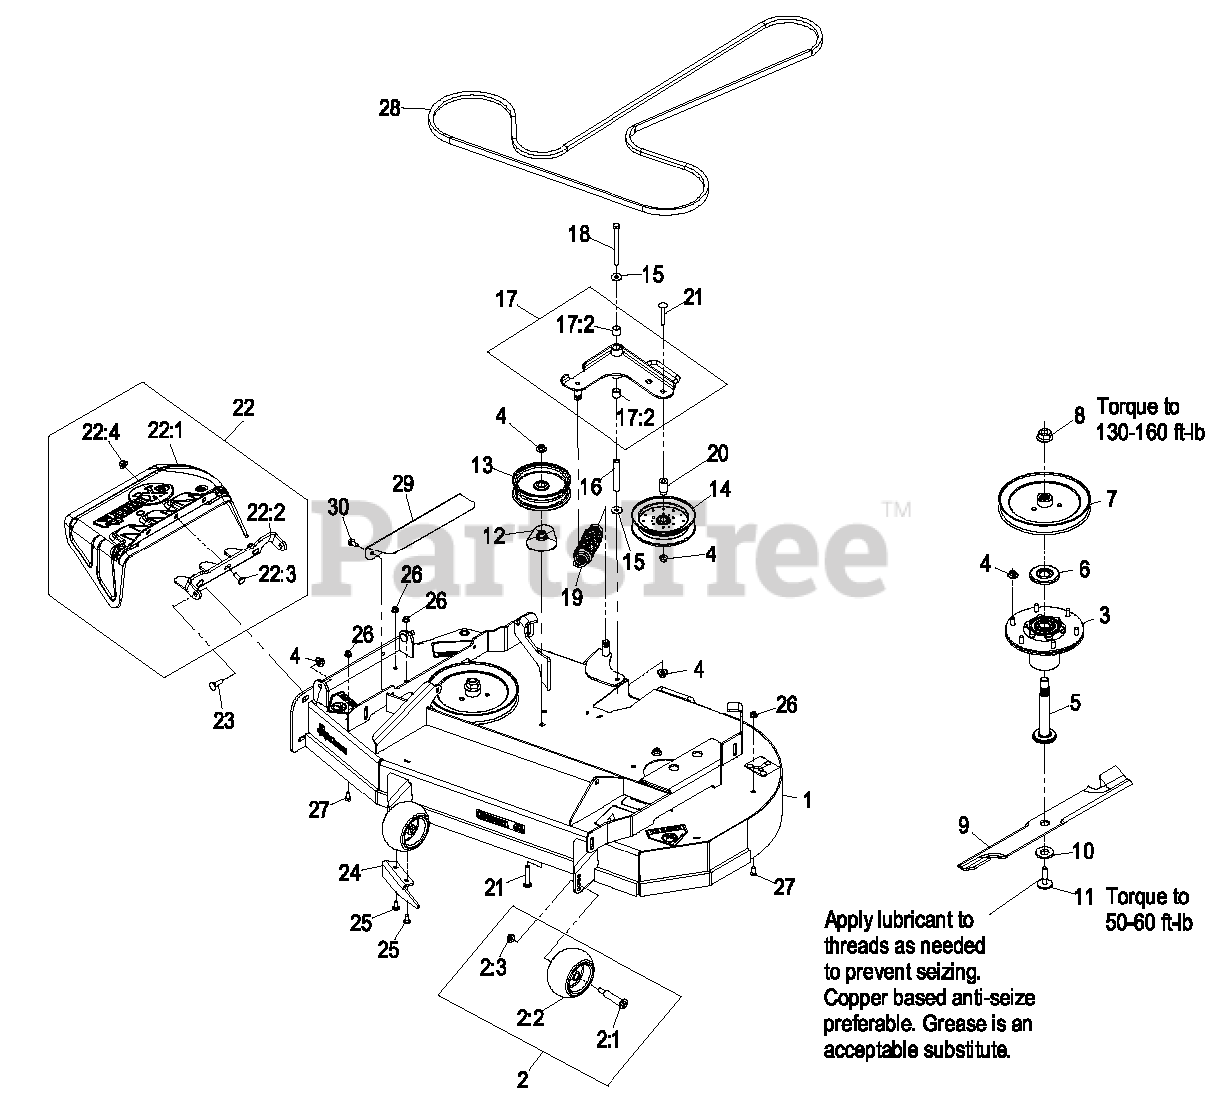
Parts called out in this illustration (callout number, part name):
1	DECK ASM-W/DECALS, 44
2	ANTI-SCALP ROLLER KIT
2:1	BOLT-SHOULDER
2:2	ROLLER-SCALP, ANTI
2:3	NUT-HF, NI
4	Nut-Nyloc 3/8-16 Flg
5	SPINDLE,HEX PILOT 5.5" DE
6	GUARD,BEARING TOP .989
7	SHEAVE-BLADE DRIVE, 8.40
8	NUT-FLANGE
9	Blade, Notched
10	WASHER-BLADE DRIVE
11	BOLT-BLADE, SEM
12	SPACER-PULLEY
16	BUSHING-TIGHTENER, PIVOT
17:2	SLEEVE-BEARING
18	SCREW-HH
20	BUSHING,IDLER
21	BOLT-CARR, SHORT NECK
22	ASM,DISCHARGE CHUTE
22:1	CHUTE,DISCHARGE
22:2	BRACKET,DISCHARGE CHUTE
22:3	SCREW-CARR
22:4	Nut-Nyloc 3/8-16 Flg
23	BOLT-CARR
24	BAFFLE-DISCHARGE
25	BOLT-CARR
26	NUT-HF, NI
27	SCREW-HH
28	BELT - V, B
29	COVER,BELT
30	Screw-HWH 5/16-18 X 3/4 Tf
